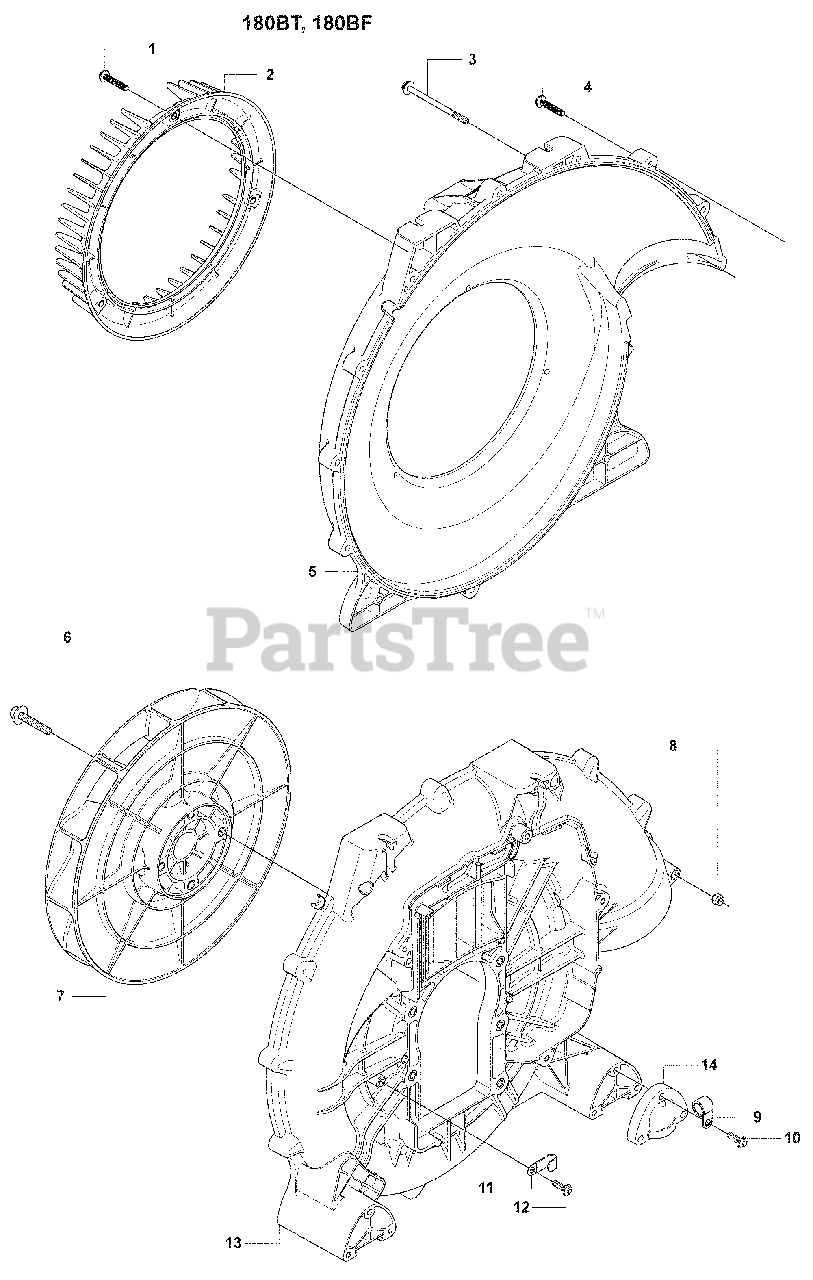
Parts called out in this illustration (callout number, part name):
1	Screw
2	COVER (FUNNEL)
4	Screw
5	VOLUTE COVER
6	Bolt
8	Nut
9	Clamp
10	Screw
11	Clamp
12	Screw
13	VOLUTE CASE
